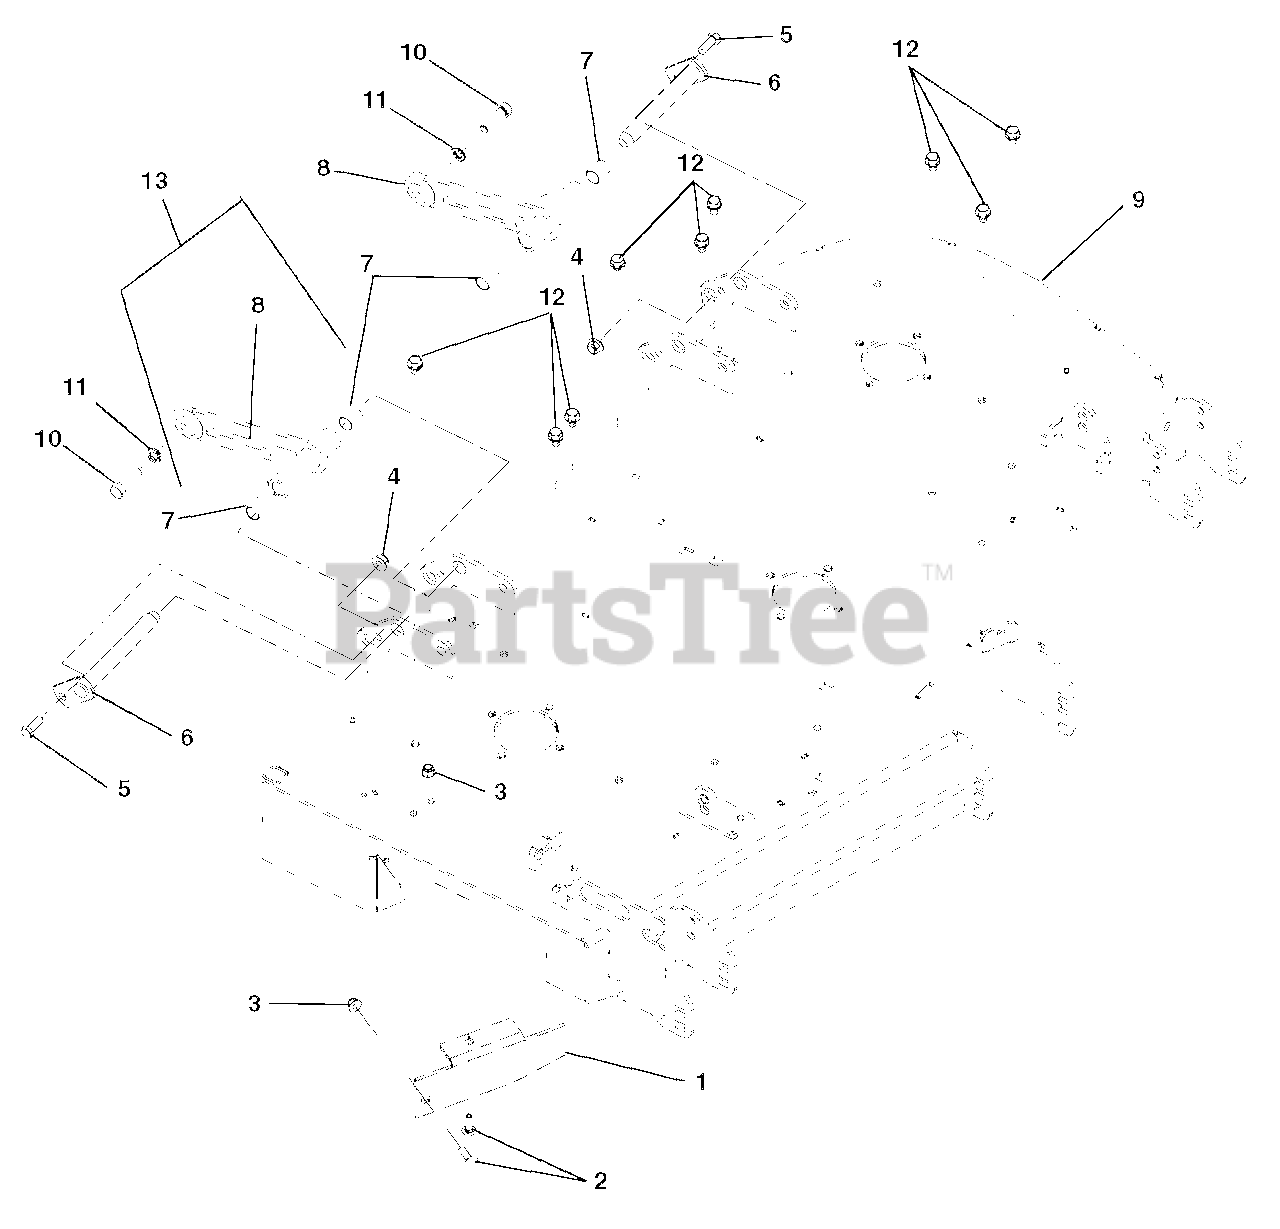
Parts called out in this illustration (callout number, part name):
1	44" - 48" Rear Discharge Baffle (076)
2	Bolt, Round Head Square Neck .31-18 x 1.00 Grade 5
3	Nut, .31-18 Nyloc Flange
4	Nut, .38-16 Nyloc Flange
5	Bolt, Hex .38-16X1.00 Grade 5
6	Weldment, Mower Mounting Pin
7	Bearing, .75 x .875 x 1.00
8	Deck Pusher Arm Weldment
9	48" 100I Side Discharge Deck (076)
10	Bolt, Hex .50-13 x 1.75 Grade 5
11	Washer, Locking .50 x .125 Regular
12	Screw, Tapping .38-16 x .50 Hex Washer Head (077, 078)
13	Assembly, Mower Mount Arm
